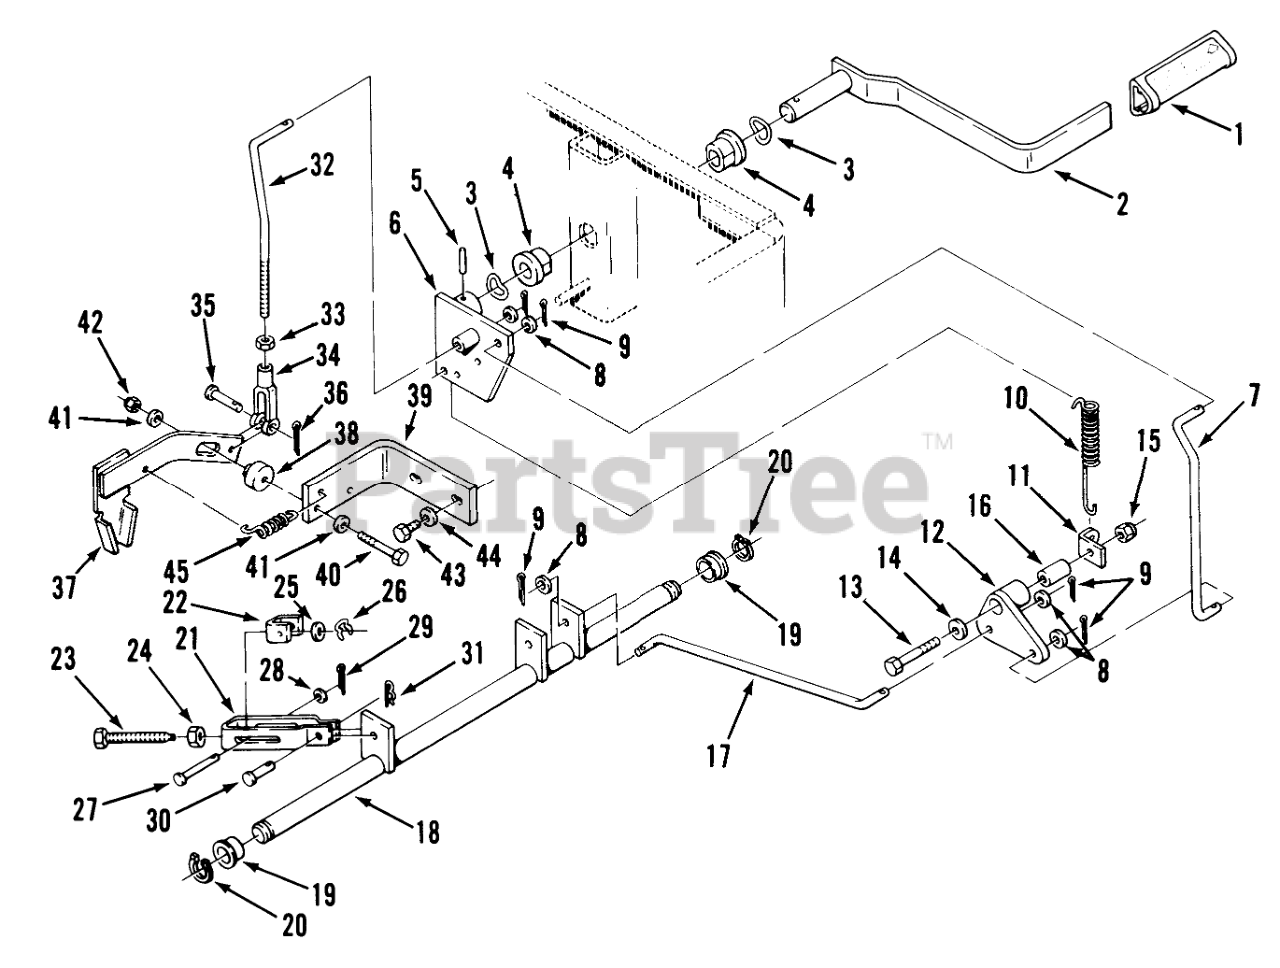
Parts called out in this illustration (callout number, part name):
1	GRIP-PARKING BRAKE
2	Brake Lever
3	WASHER-BOWED
4	BEARING-FLANGED
5	Roll Pin
6	Arm
7	ROD BRAKE UPPER
8	WASHER 5/16 SAE
9	Cotter Pin
10	SPRING-EXTENSION
11	CLIP - SPRING
12	WLMNT-BRAKE PIVOT
13	Bolt
14	Washer
15	NUT
16	SPACER
17	ROD BRAKE LOWER
18	WLMNT-BRAKE SHAFT R
19	BUSHING
20	RING-SNAP, EXTERNAL
21	WLMT BRAKE YOKE A R
22	YOKE-BRAKE ADJUST R
23	BOLT-ADJUSTER
24	Nut
25	WASHER
26	CLIP-RING 1/4"
29	Cotter Pin 1/16 x 3/4
30	Clevis Pin 5/16 x 5/8
31	Hairpin
32	ROD-NEUTRAL LOCK
33	Nut
34	CLEVIS
36	Cotter Pin
37	Lock-Neutral
38	SPACER
39	Bracket-Support
40	Screw-Hex. Hd.
41	WASHER
42	Nut
43	Screw
44	WASHER 5/16 SAE
45	SPRING-EXTENSION
